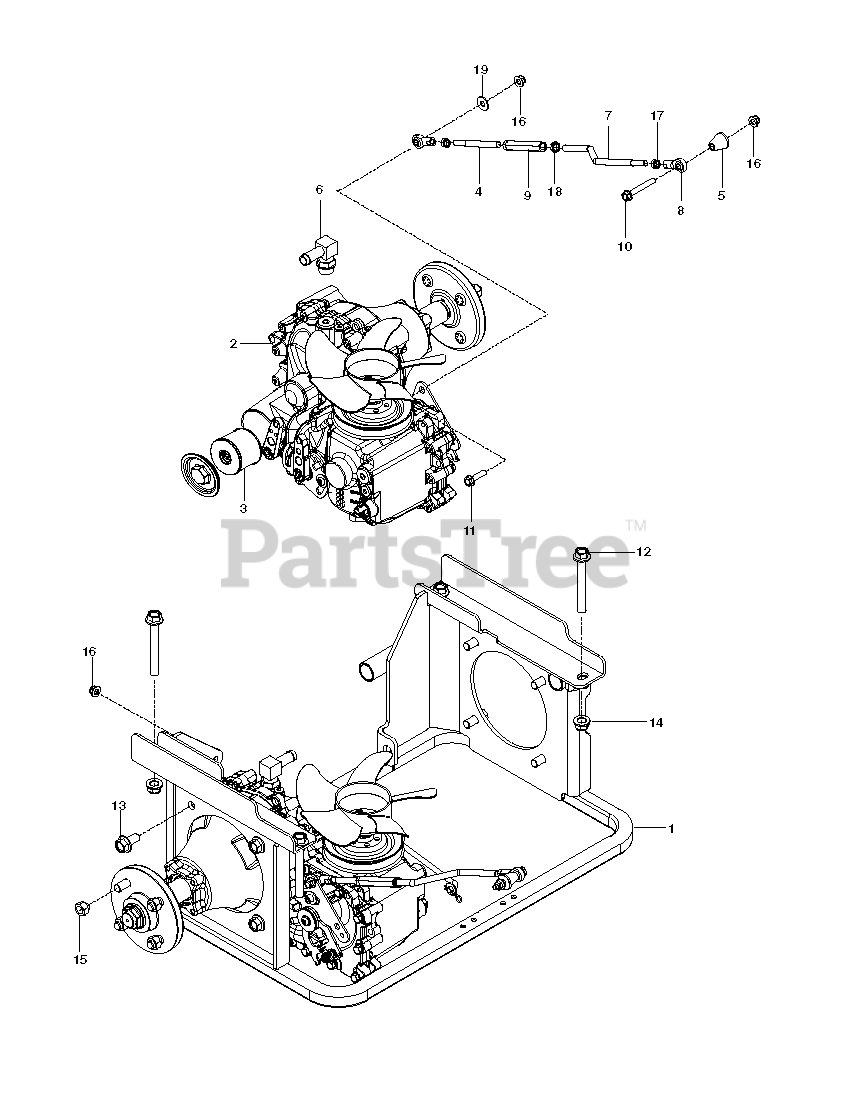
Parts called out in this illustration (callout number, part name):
2	HG_ZT5400 RT NON 2-SPEED
4	LINKAGE, CONTROL, FT
8	BALL JOINT, RIGHT HANDED
9	TURNBUCKLE, 3/8
10	HHFS 5/16-18 X 2.25 GD 5
11	HHFS 5/16-18 X 1.25 TPBLT GD 5
12	HHFS 1/2-13 X 4.0 GD8 ZD
14	NUT, 1/2-13 HEX FLG NYLOC ZD
15	LUG NUT 1/2F
16	5/16-18 NYLOC FLANGE NUT
17	NUT 5/16F
18	NUT 3/8-24 JAM
19	WASHER 5/16 FLAT
